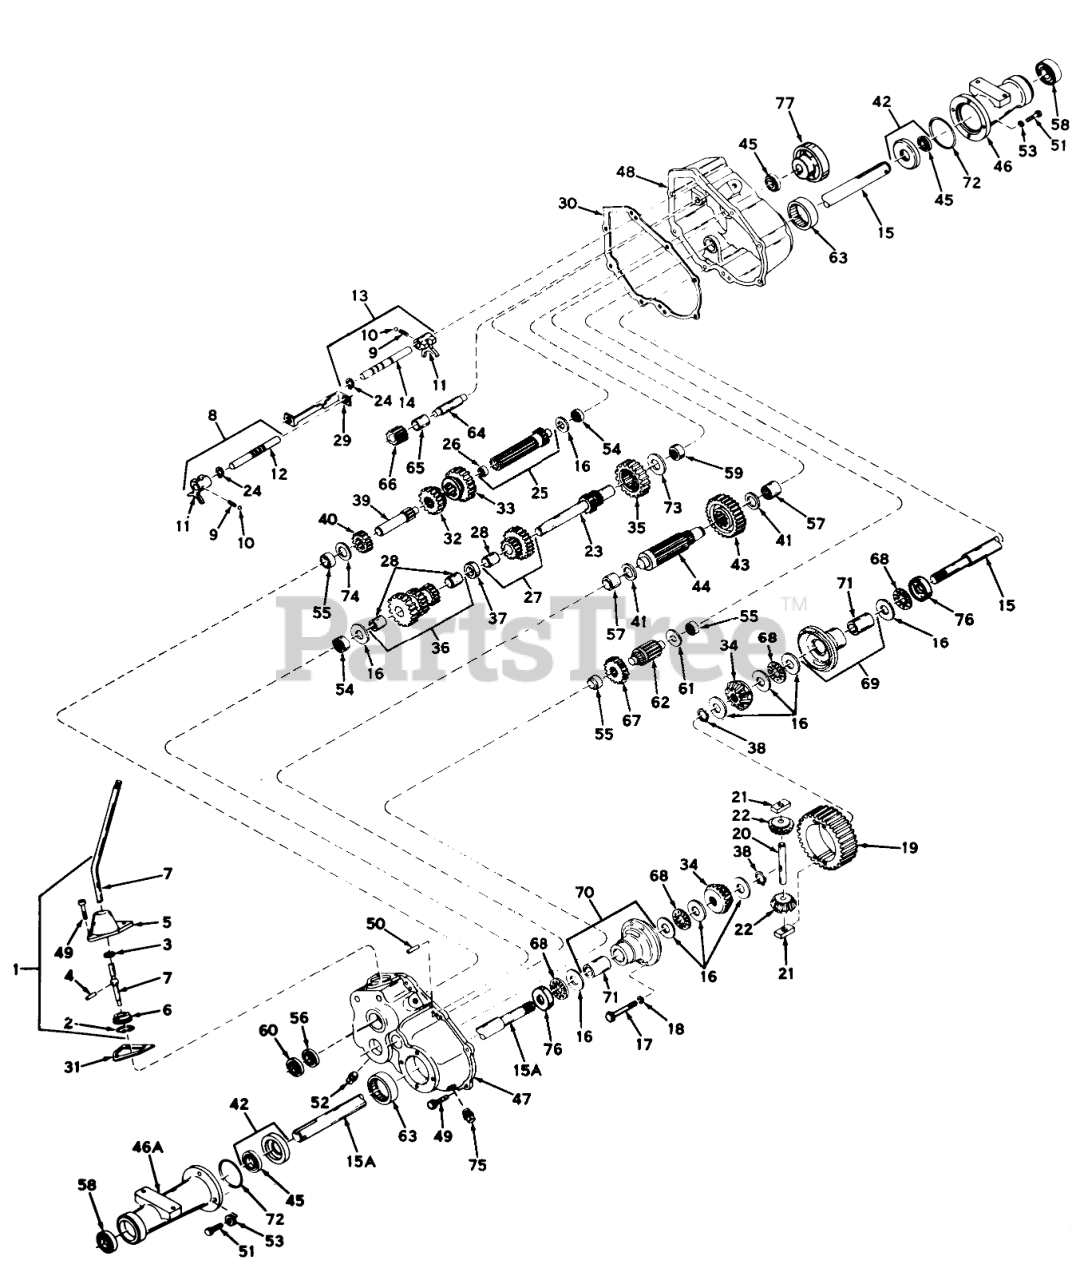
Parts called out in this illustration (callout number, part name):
1	Lever & Housing Assy., Shift (Incl. Nos. 2 thru 7)
2	Ring-Snap
3	O Ring
4	Roll Pin
5	Housing-Shift Lever
6	Keeper-Shift Lever
7	Lever, Shift
8	Rod Assy., Shift (Incl. Nos. 9 thru 12 & 24)
9	Spring
10	Piston ASM
11	Shift Fork
12	Rod, Shifter
13	Rod Assy., Shift (Incl. Nos. 9, 10, 11, 14 & 24)
14	Rod, Shifter
15	Axle, R.H.
15A	Axle, L.H.
16	Washer
17	Screw (1/4-20 x 2-1/2)
18	Lockwasher
19	Gear, Ring
20	Pin-Drive
21	Biock-Drive
22	Pinion, Bevel
23	Shaft & Gear, Brake
24	Ring-Snap
25	Shaft & Bearing Assy., Pinion (Incl. No. 26)
26	Bearing
27	Gear Cluster Assy. (Incl. No. 28)
28	Bushing
29	Stop-Shifter
30	Gasket-Case & Cover
31	Gasket-Lever Housing
32	Gear, Shifting
33	Gear, Shifting
34	Gear, Bevel
35	Gear-Spur
36	Gear Cluster Assy. (Incl. No. 28)
37	Spacer
38	Ring-Snap
39	Shaft, Input
40	Gear (10 teeth)
41	Washer-Thrust
42	Seal & Retainer Assy., Oil (Incl. No. 45)
43	Gear-Output
44	Pinion-Output
45	Seal-Oil
46	Housing, R.H. Axle
46A	Housing, L.H. Axle
47	Case Assy., Transaxle (Incl. Nos. 54, 55, 57 & 63)
48	Cover Assy., Transaxle (Incl. 54, 55, 57, 59 & 63)
49	Screw
50	Dowel Pin
51	Screw (5/16-18 X 7/8)
52	Plug-Magnetic Drain
53	Lockwasher
54	Bearing-Needle
55	Bearing, Needle
56	Bearing
57	Bearing-Needle
58	Bearing-Ball
59	Bearing-Needle
60	Seal-Oil
61	Washer
62	Shaft & Pinion
63	Bearing Needle
64	Shaft-Reverse Idler
65	Spacer-Reverse Idler
66	Idler Reverse
67	Gear-Spur (22 Teeth)
68	Bearing-Thrust
69	Carrier Assy., Differential (Incl. No. 71)
70	Carrier Assy., Differential (Incl. No. 71)
71	Bushing
72	O-Ring
73	Washer-Thrust
74	Washer
76	Race-Thrust
77	Drum, Brake
